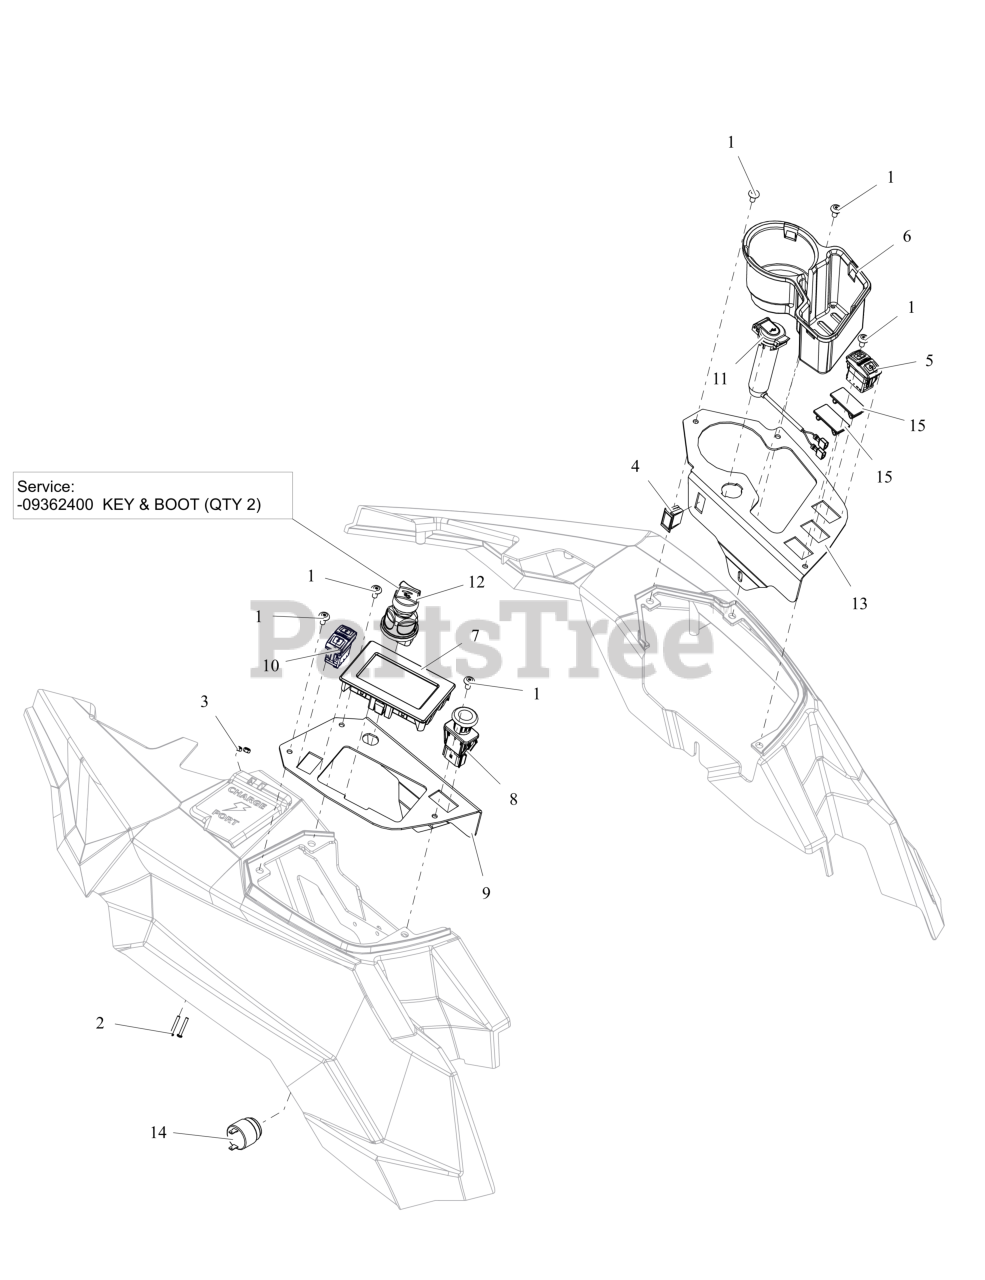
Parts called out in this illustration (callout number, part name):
1	SCR, MCH .25-20 X .500 TXTR ZB500
2	SCR, PH PAN HD #6-32X1.000 ZCC
3	@NUT-LK-NYL 6-32 W/INSRT YWZC
4	SWITCH,BLANK
5	SWITCH, TOGGLE - SPEED
6	HOLDER, CUP
7	DISPLAY, GRAVELY
8	SWITCH, PTO (SEALED)
9	PANEL, CONTROL -RH (RED)
10	SWITCH, ROCKER - DISPLAY
11	PLUG, CHARGER USB
12	SWITCH, KEY (SEALED)
12	KEY & BOOT (QTY 2)
13	PANEL, CONTROL -LH (RED)
14	ALARM, AUDIBLE
15	PLUG, SWITCH
